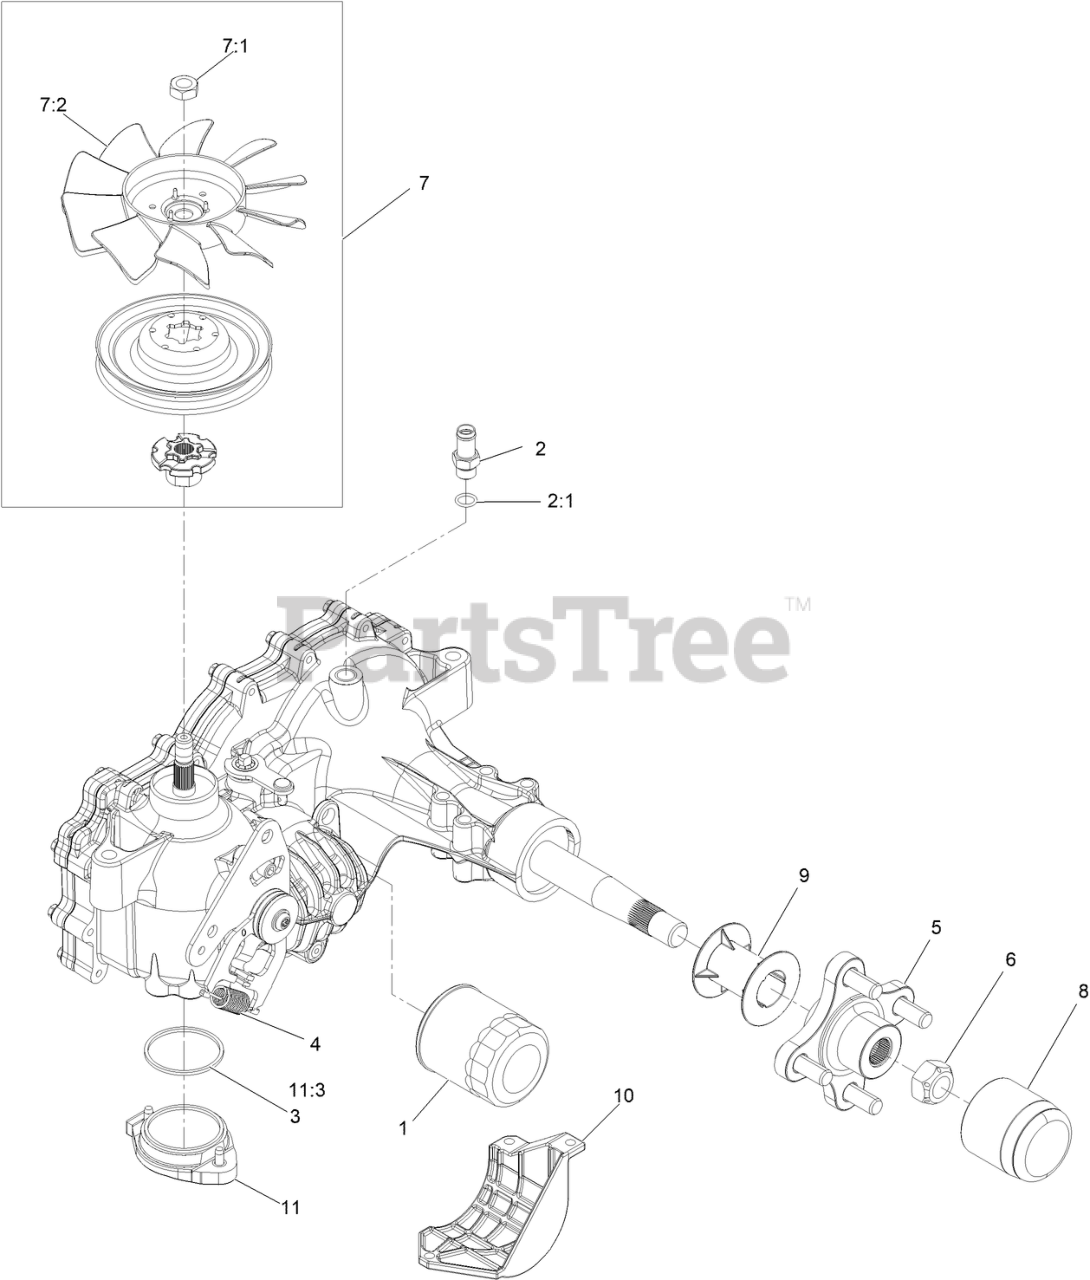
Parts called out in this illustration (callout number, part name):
1	ELEMENT-OIL FILTER, HYD
2	ADAPTER-STRAIGHT
2:1	O-RING
3	O RING-SEAL
4	SPRING-EXTENSION
5	HUB-OFFSET
6	NUT-HUB
7	FAN AND PULLEY KIT
7:1	NUT-HJ
8	CAP-AXLE, LONG
9	TUBE-AXLE
10	GUARD-FILTER, LH
11	CHARGE KIT
11:3	O RING-SEAL
99	BRAKE SHAFT SEAL KIT
